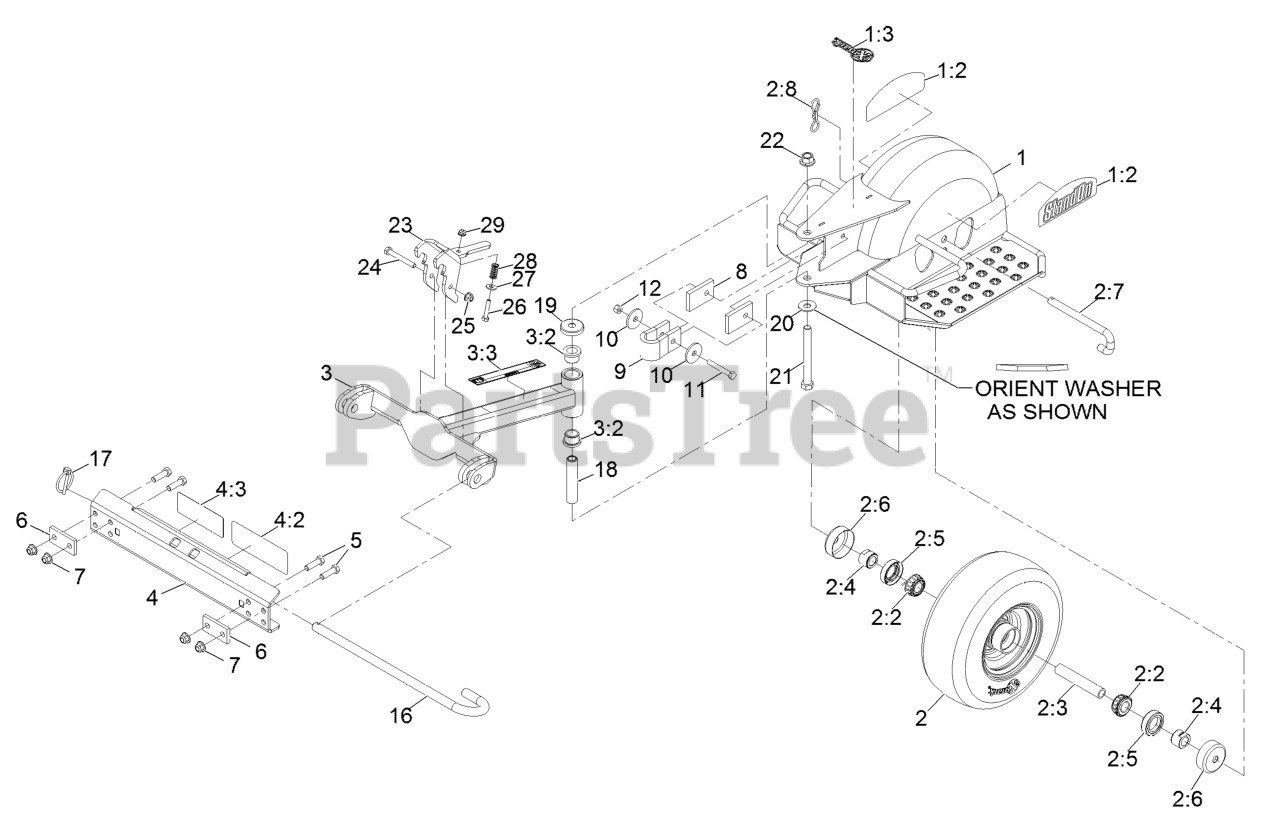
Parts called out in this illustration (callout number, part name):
1:2	DECAL,STANDON
1:3	DECAL,EXMARK
2	ASM, WHEEL AND BEARINGS
2:2	BEARING-CONE, TAPERED ROLLER
2:4	SPACER-NUT
2:5	SEAL-CASTER
2:6	GUARD-SEAL
2:7	PIN, CASTER
2:8	PIN-COTTER, LOCKING
3:2	BUSHING, PIVOT
3:3	DECAL,SULKY
4:2	DECAL,BELT DRIVE
4:3	DECAL,SULKY WARNING
5	SCREW-HH
6	PLATE,BACK-UP (PLATED)
7	NUT-HF, NI
8	PAD,STOP
11	SCREW-HH
12	NUT-LOCK, NI
16	PIN, PIVOT
17	PIN-LYNCH
18	SPACER, PIVOT
19	COVER, DUST
20	WASHER-SPRING
21	WASHER-LOCK
22	Nut-Lock 1/2-13
23	Latch, Transport
24	SCREW-HH
25	NUT-HF, NI
26	SCREW-HH
27	WASHER-FLAT
28	SPRING, COMPRESSION
